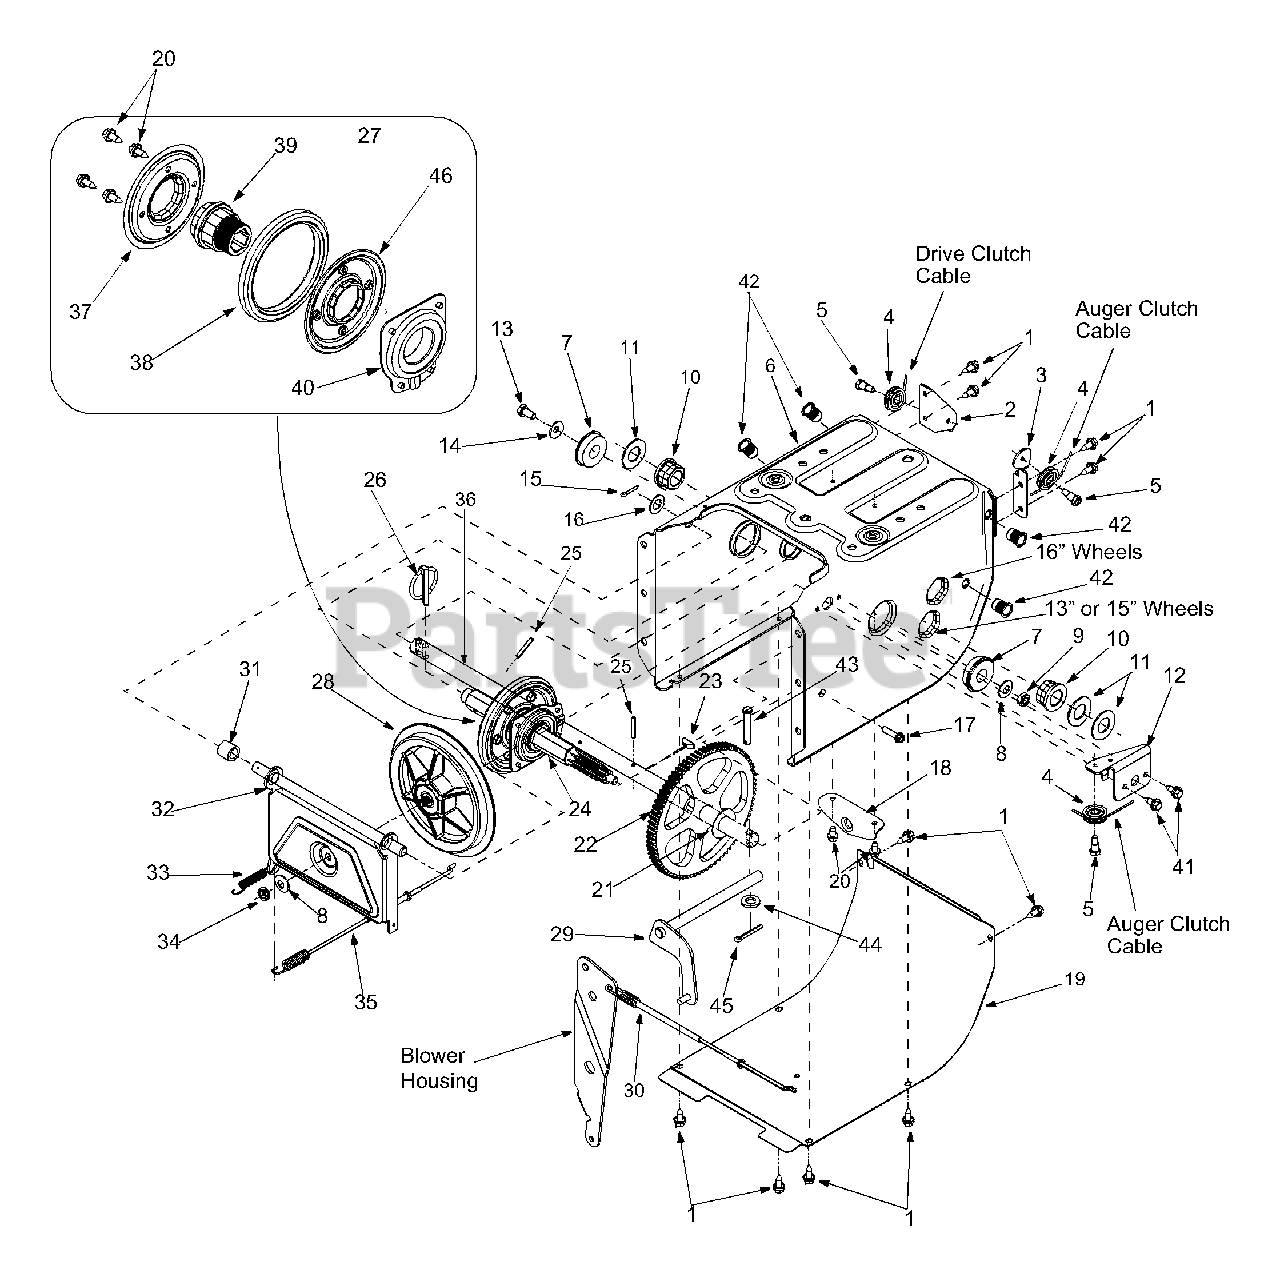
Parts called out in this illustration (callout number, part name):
1	Hex Screw
5	Hex Screw 1/4-28
6	Frame Assembly
7	Ball Bearing
8	Bell Washer
9	Lock Jam Nut
10	Hex Flange Bearing
11	Flat Washer
14	Bell Washer .340 ID x .872 OD
15	Cotter Pin
16	Flat Washer .536 ID x .930 OD
17	Hex Washer Screw 1/4-20
21	Flat Washer .760 ID x .50 OD
24	7-Tooth Shaft
25	Roll Pin
26	Klik Pin
27	Friction Wheel Assembly
28	Friction Disc Wheel
29	Wheel Shift Rod Assembly
30	Drive Cable, Auger
31	Spacer
34	Jam Nut 3/8-24
35	Drive Cable, Clutch
36	Axle 13" Wheels
36	Axle 16" Wheels
37	Friction Plate
38	Friction Wheel Rubber
39	Friction Wheel Hub
40	Friction Wheel Bearing
41	Tap Screw 1/4-20
42	Insert Nut 5/16-18
43	Clevis Pin
44	Flat Washer .281 ID x .50 OD
45	Cotter Pin
